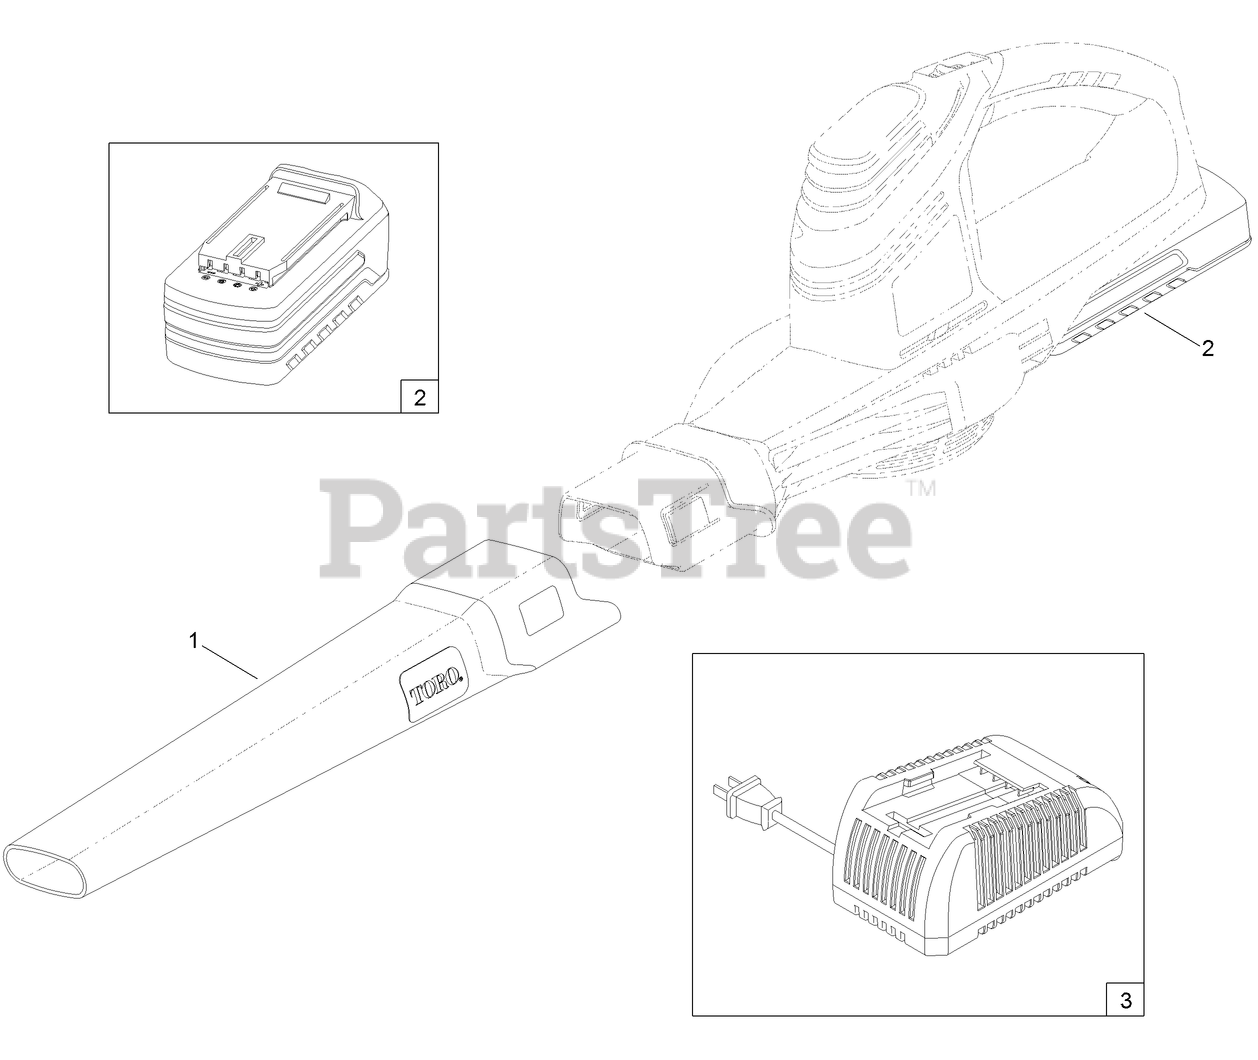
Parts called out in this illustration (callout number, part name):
1	TUBE-OUTLET, SWEEPER
2	BATTERY-LI-ION, 24V, 2.0AH
3	CHARGER-24V, LI-ION BATTERY
